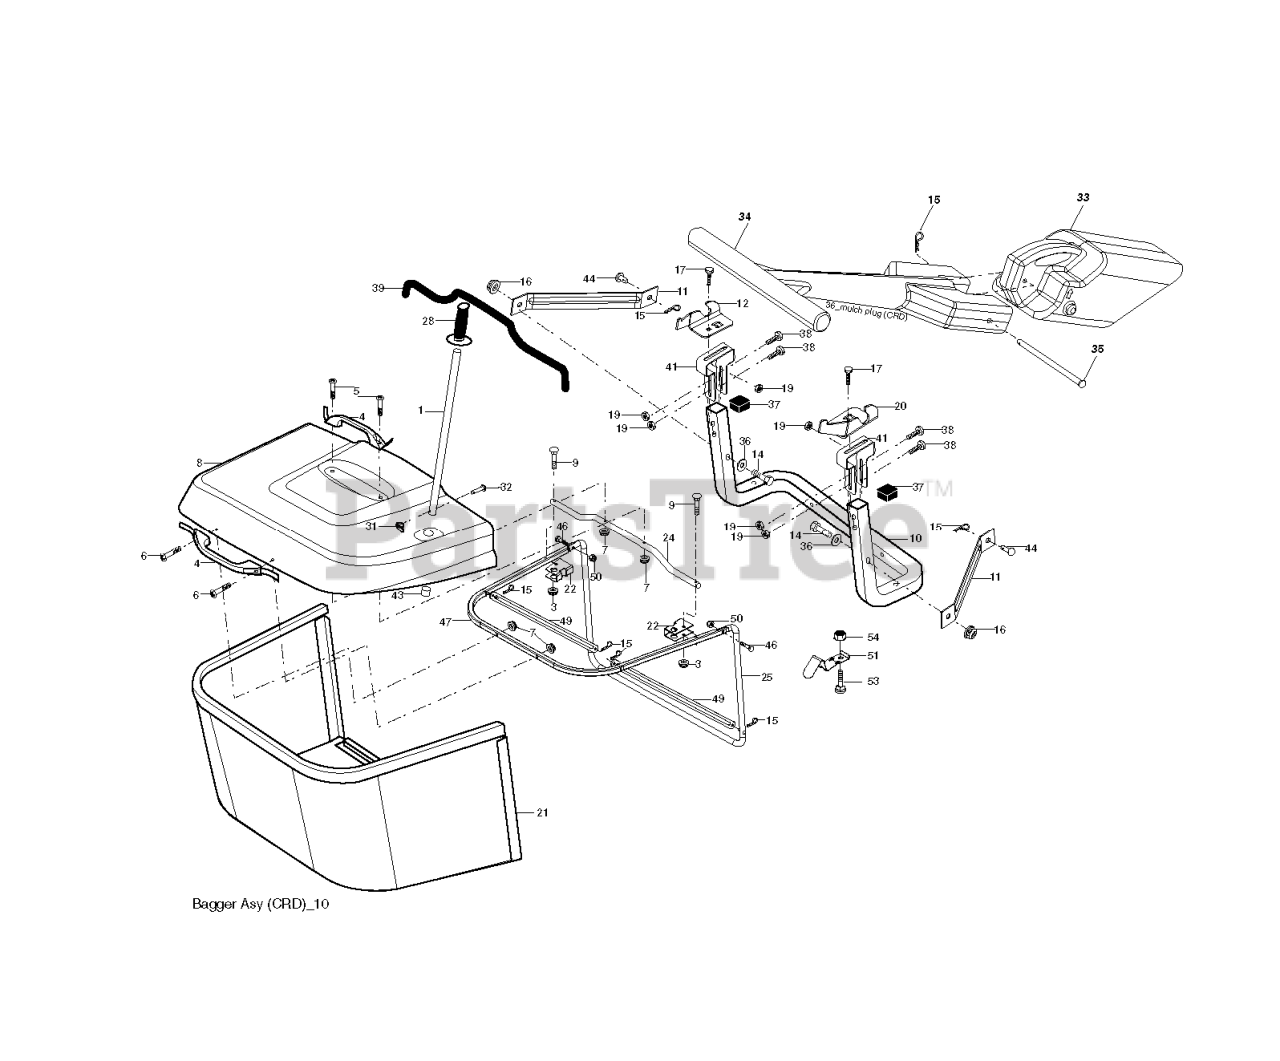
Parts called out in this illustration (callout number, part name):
1	TUBE HANDLE
3	NUT T
4	HANDLE.BAGGER.W/LVRS.BLK.CRD
5	SCREW.PAN.HEAD
6	REPL BY 532 75 00-29
8	COVER.PNT.BGR.CRD.WSLOTS.MS668
9	Bolt Carriage 1/4-20 x 2.25d x Gr.5
10	TUBE
11	BRACKET.SUPPORT.UPPER.BAG.CRD
12	BRKT PIVOT
14	BOLT-HEX EAK
15	RETAINER-SPRNG RB
16	NUT LOCK FLG 3/8-16 UNC
17	RP BOLT 5/16-18 X3/4 ZN/YEL GR
19	NUT LOCK HEX FLANGE 5/16-18
20	BRKT.PIVOT.RH.CRD
21	BAGGER.ASM.CRD.2007
22	BRKT.SIDE.BAG.CRD
24	TUBE.PIVOT.BAG.CRD.BLACK
25	PIPE
28	GRIP.HANDLE.BLACK
31	RETAINER CLIP
32	RIVET,DRILLED
33	MULCH PLUG, CTH150
34	HANDLE.MULCHER.92.CRD (2 2)
36	WASHER
37	Plug Support Bagger CRD
38	BOLT.5/16-18X2.5
39	SEAL.TRIM.37'
41	BRKT.VERT.ADJ.BAGGER.CRD
43	PLUG, TUBING END
46	BOLT.CARRIAGE.5/16-18
47	PIPE
49	ROD
50	NUT.71038.31-18.HEX.NYLOCK
51	LATCH
53	NUT
54	BOLT
